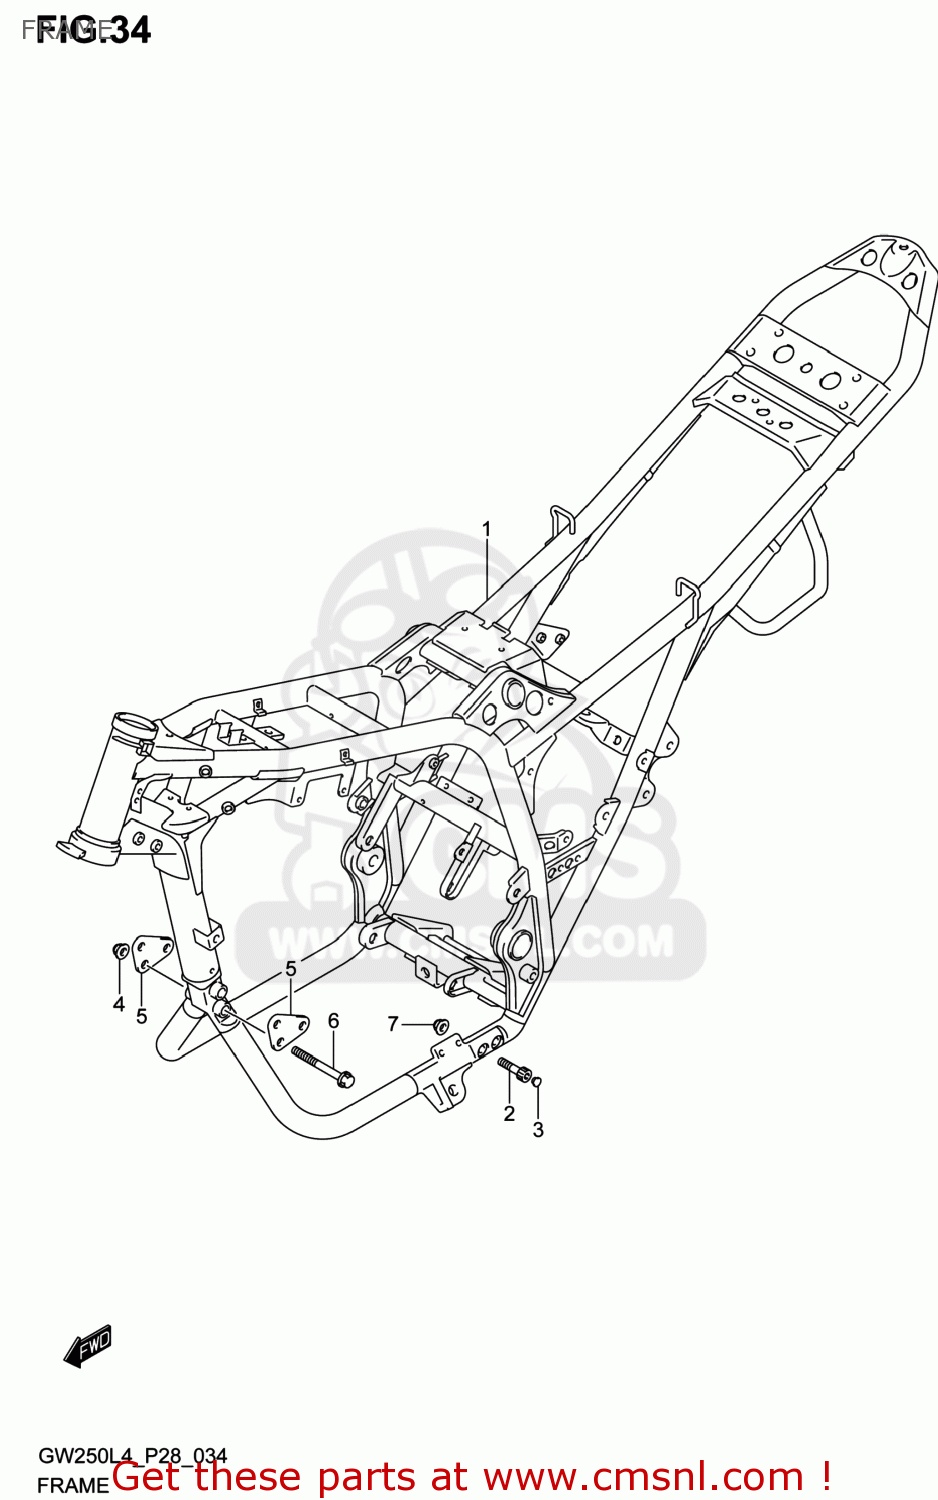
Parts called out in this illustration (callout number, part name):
1	FRAME
2	BOLT(10X37)
3	CAP(OD:12)
4	NUT
5	BRACKET,ENGINE MOUNTING FR
6	BOLT(10X85)
7	NUT
